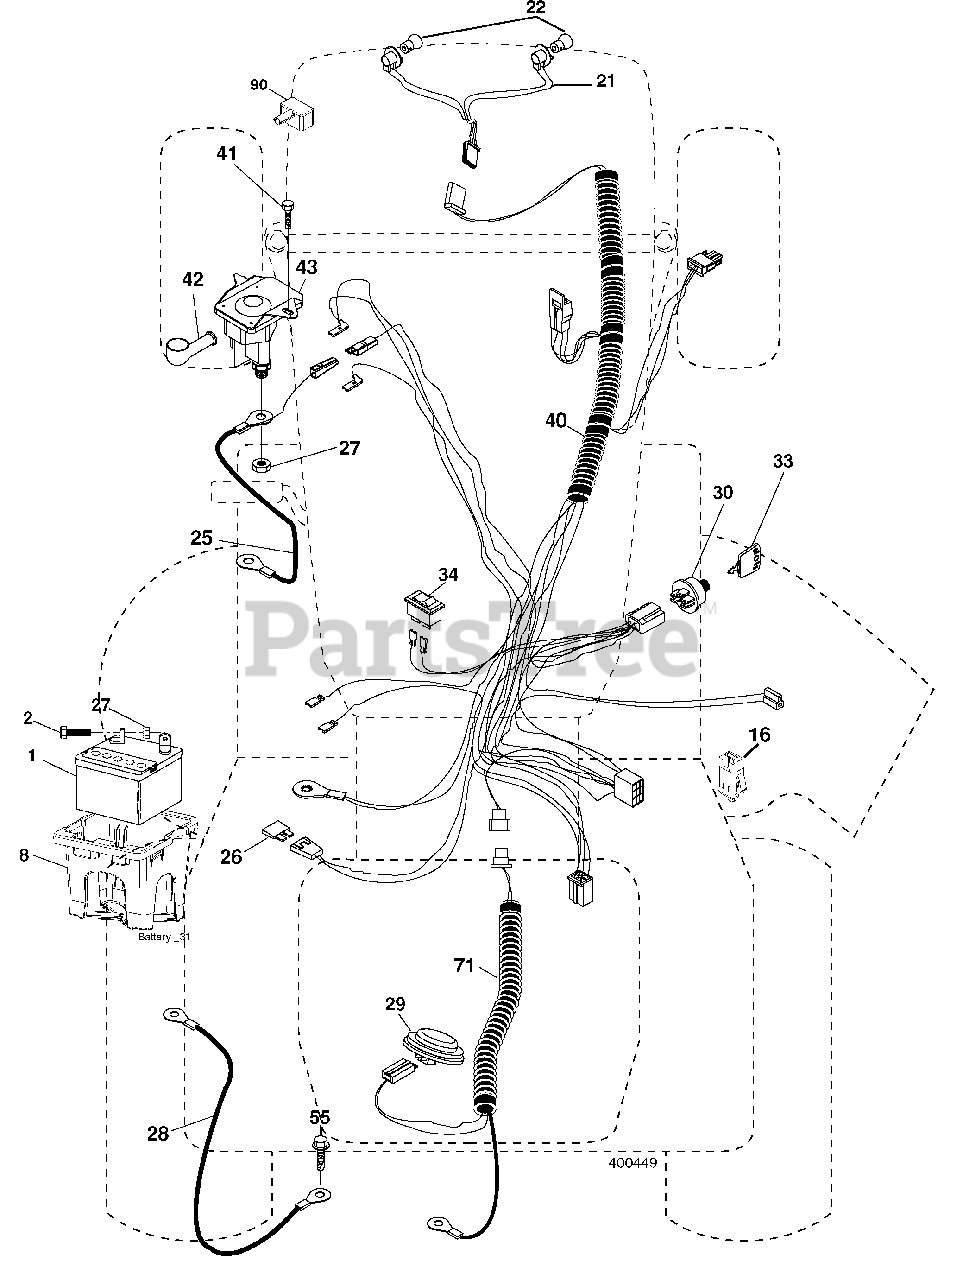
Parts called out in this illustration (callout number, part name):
1	Battery
2	Bolt Hex Hd 1/4-20 unc x 3/4
8	Box Battery
16	Switch Interlock
21	Harness Socket Light
22	Bulb, Light # 1156
25	Cable Battery 6 Ga. Red 14.5
26	Fuse
27	Nut Keps Hex 1/4-20 unc
28	Cable Ground 18" Rear Battery Blk 6 Ga.
29	Switch Seat
30	Switch Ign
33	Key Ign Molded Generic
34	Switch Light/Reset
40	Harness Ign
41	Screw 1/4-20 unc x 1/2
42	Cover Terminal Red
43	Solenoid
55	Screw 5/16-18 x 3/4
71	Harness Ign. Chass.
90	Cover Terminal
92	Harness Pigtail Reverse Switch
93	Screw Plastic 10-14 x 2.0
94	Modual Reverse ROS
